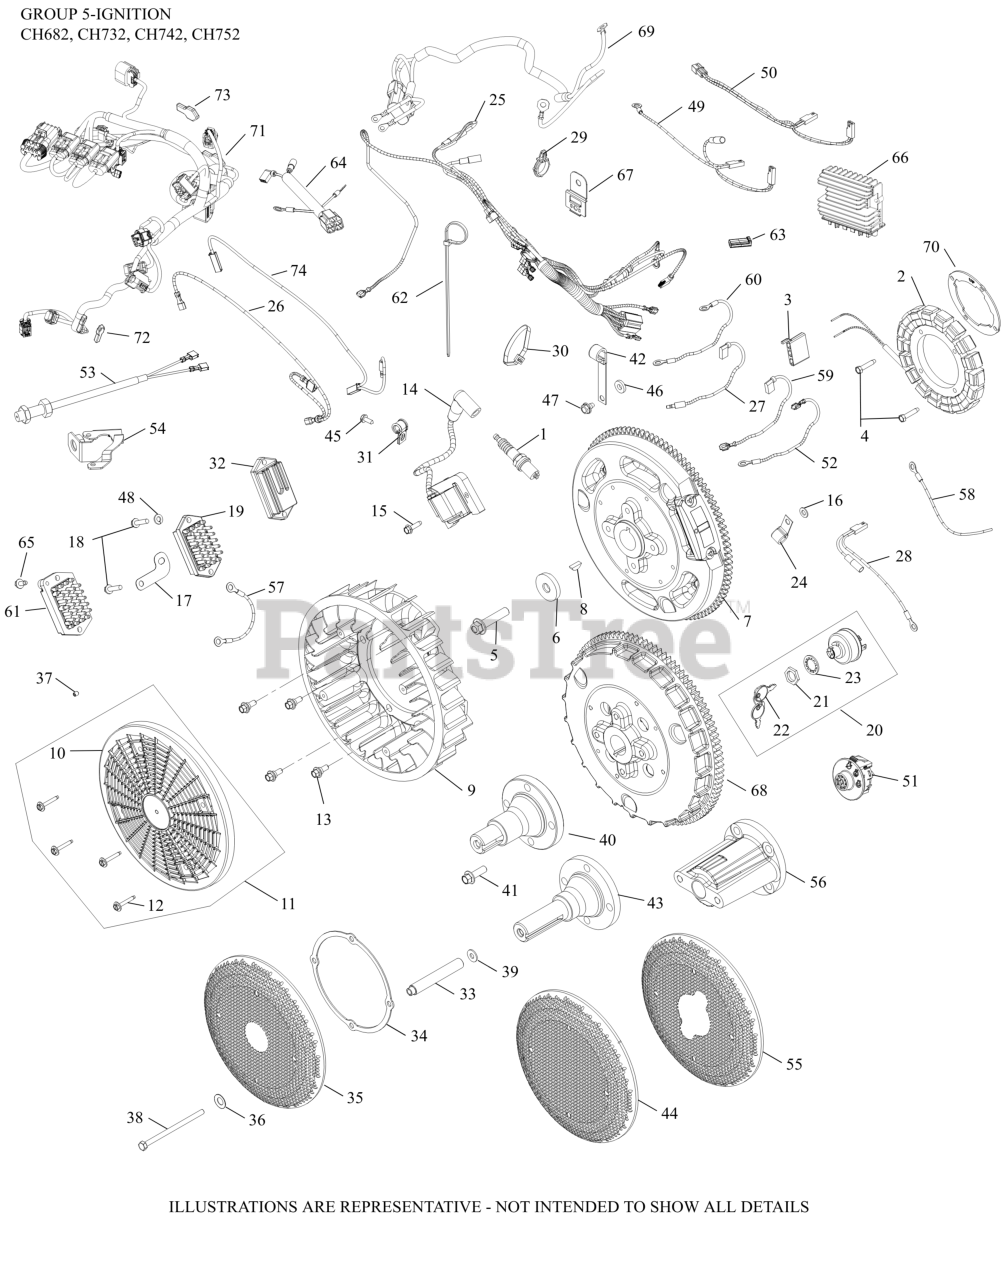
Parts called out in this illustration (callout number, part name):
1	SPARK PLUG, RFI
2	KIT, 15 / 20 AMP STATOR
3	CONNECTOR
4	SCREW, THREAD FORMING
5	SCREW, FLG M10X1.5X45-USE 25 086 361-S
6	WASHER, FLAT 13/32"
7	FLYWHEEL ASSEMBLY (LW)
8	KEY, 3/16" X 5/8"
9	FAN-USE 24 755 253-S
10	SCREEN, GRASS
11	KIT GRASS SCREEN
12	SCREW, FLG SEMS M4x.7x25
13	BOLT, SHOULDER
14	MODULE, MAG DIGITAL IGN-(#24584178S)
14	MODULE, MDI-USE 24 584 108-S
15	SCREW, THREAD FORMING
16	WASHER, FLAT 1/4" (O.D. 1/2")
18	SCREW, HEX FLANGE HI-LO
22	KEY, SET OF 2
24	CLIP, CABLE
25	HARNESS, WIRING ASSEMBLY
26	LEAD, DUPLEX
27	LEAD, OIL SENTRY
28	LEAD, JUMPER (H/S)
29	RETAINER, WIRE HARNESS
51	KIT, KEY SWITCH (SNAP-IN)
52	LEAD, 20/25 AMP B+
61	REGULATOR, RECT (20-30AMP, FW W/OVP)
65	SCREW, THREAD FORMING
